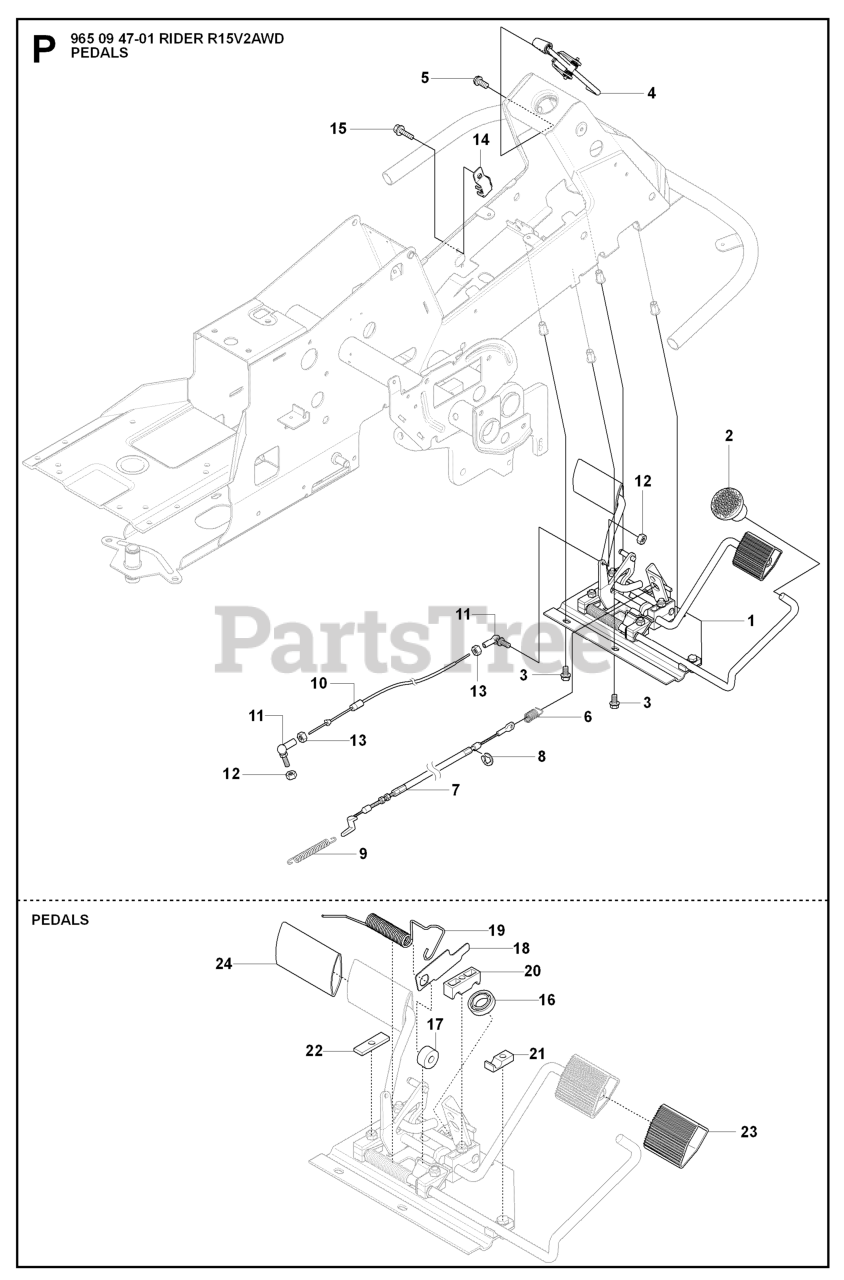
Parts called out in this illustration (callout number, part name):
1	PEDAL ASSEMBLY
2	KNOB
4	BRAKE LEVER ASSY
7	RP WIRE
10	%WIRE
11	CONNECTOR
12	LOCKNUT M5
14	BRACKET
16	BALL BEARING 6002-2RS1
17	ROLLER
18	PLATE
19	SPRING
20	PEDAL SHAFT CLAMP
21	SUPPORT
22	PLATE
23	PEDAL RUBBER
24	PEDAL RUBBER, SF
